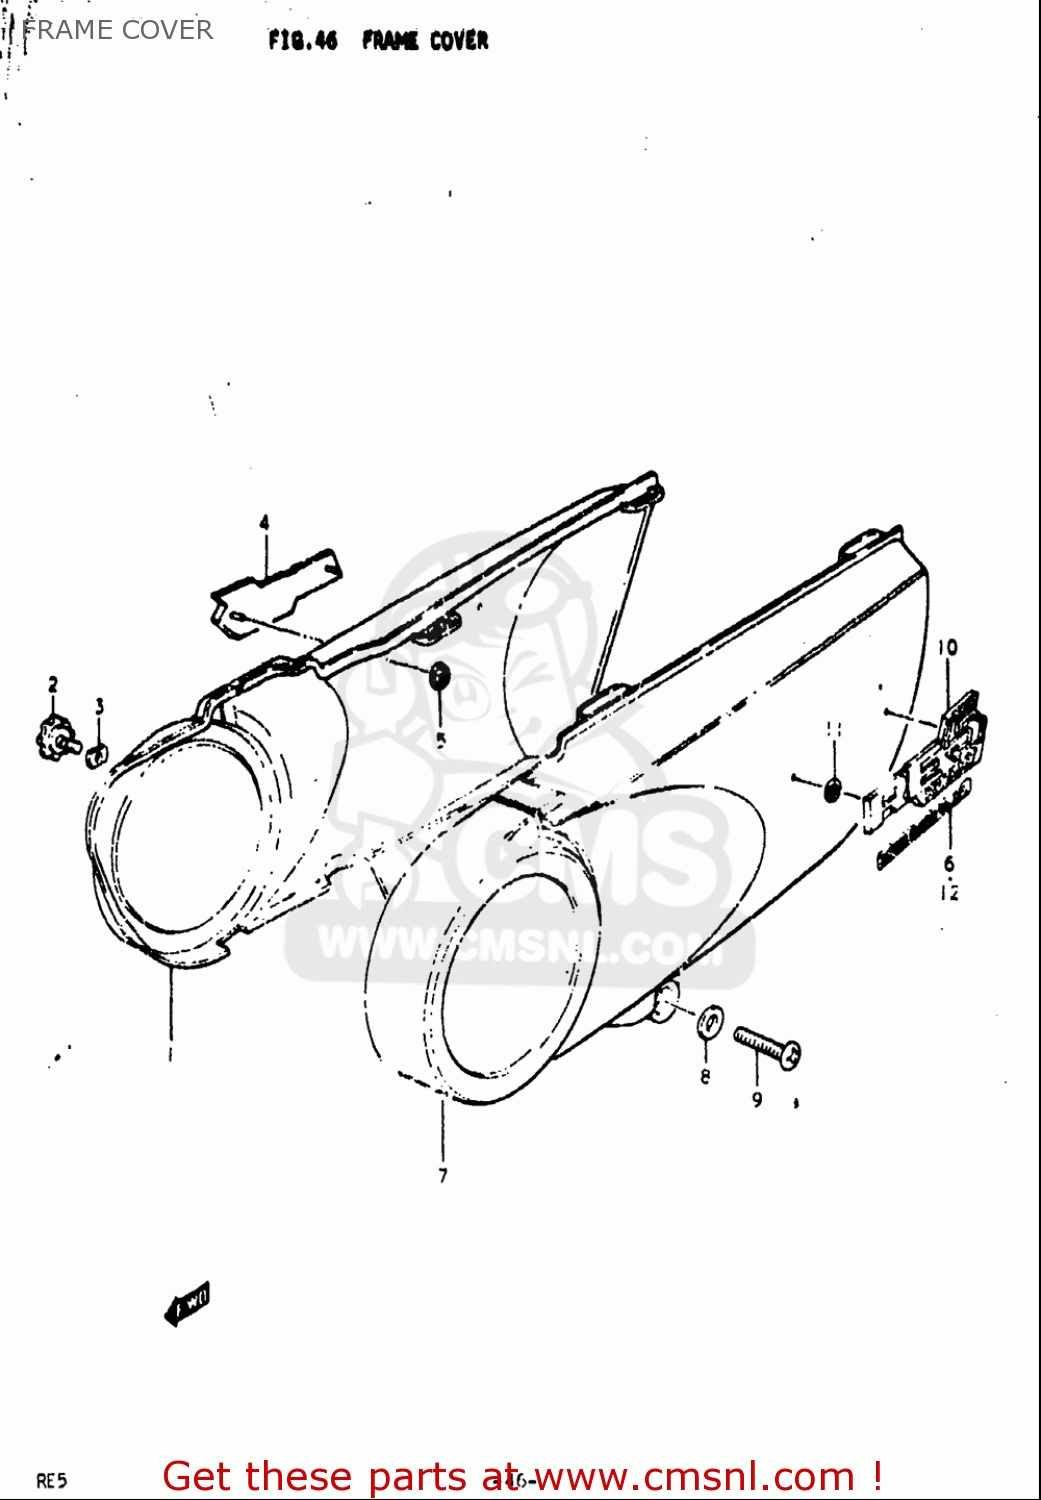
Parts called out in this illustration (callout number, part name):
1	COVER,FRAME,RIGHT
2	KNOB,FRAME COVER,R
3	NUT
5	NUT
8	WASHER(6.5X18X1.6)
9	SCREW
11	NUT
